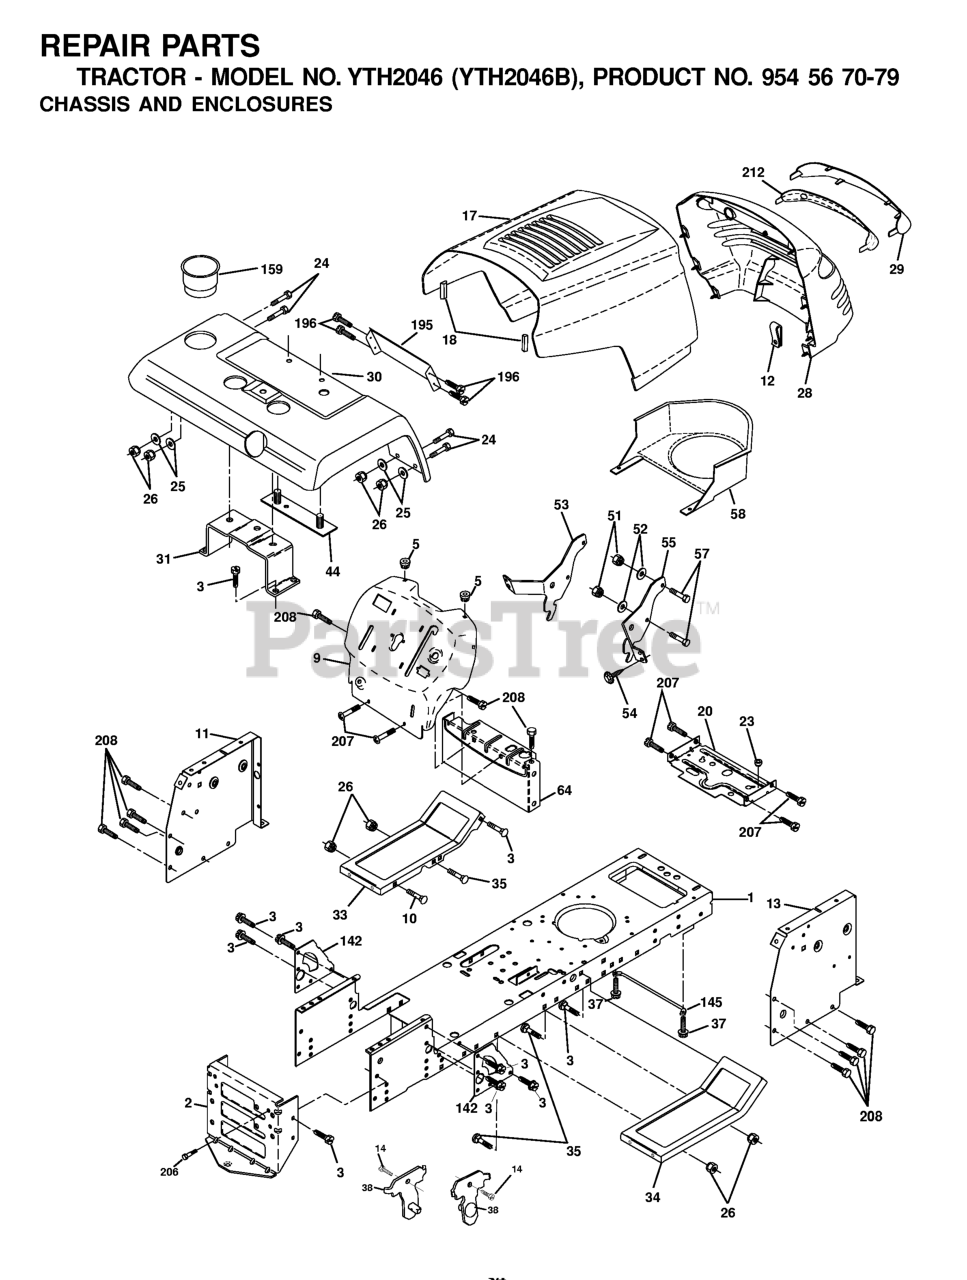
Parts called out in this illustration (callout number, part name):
1	CHASSIS STAMPING
2	DRAWBAR, 12GA
3	SCREW 3/8-16X3/4
5	BUMPER.RUBBER.HOOD
9	DASH SLKSCR
10	BOLT D
11	PANEL DASH LH
13	PANEL ASM, DASH RH
17	HOOD ASM.
18	BUMPER HOOD T
20	PLATE MTG
23	BUSHING.SNAP.NYL.BLK.
25	WASHER
26	NUT
28	GRILLE ASM
29	LENS
31	BRACKET ASM, FENDER
33	FOOT REST LH
34	FOOTREST RH
37	Screw 5/16-18 x 1/2 Hex, Self Tapping 5/16-18 x 1/2
38	BRACKET
44	STRAP
51	LOCKNUT.NYLOC.1/4-20
53	BRACKET.GRILLE.LH
54	SCREW.HEX.WS.HD.8-18 X 7/8
57	BOLT
58	DUCT, INTAKE AIR
64	DASH LOWER
142	PLATE
145	ROD PIVOT CHASSIS/HOOD
196	SCREW CRT
206	SHOULDER BOLT 5/16-18TT
207	SCREW, 5/16-18 X 1/2
208	SCREW 3/8-16X1/2
212	REPL BY 532 1745-03
